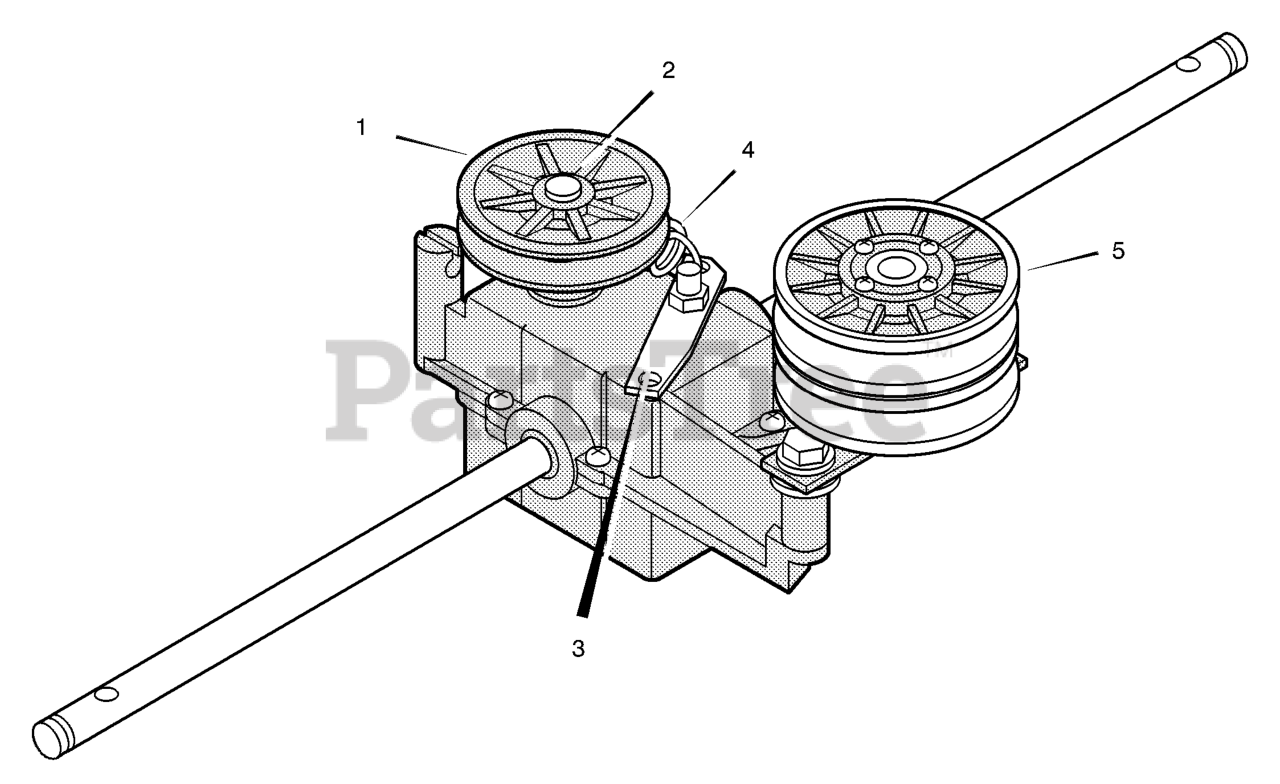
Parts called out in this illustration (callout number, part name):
1	Pulley
2	Attachment Pin, Pulley
3	Clutch Lever Assembly
4	Spring, Clutch Return
5	Variator Assembly
